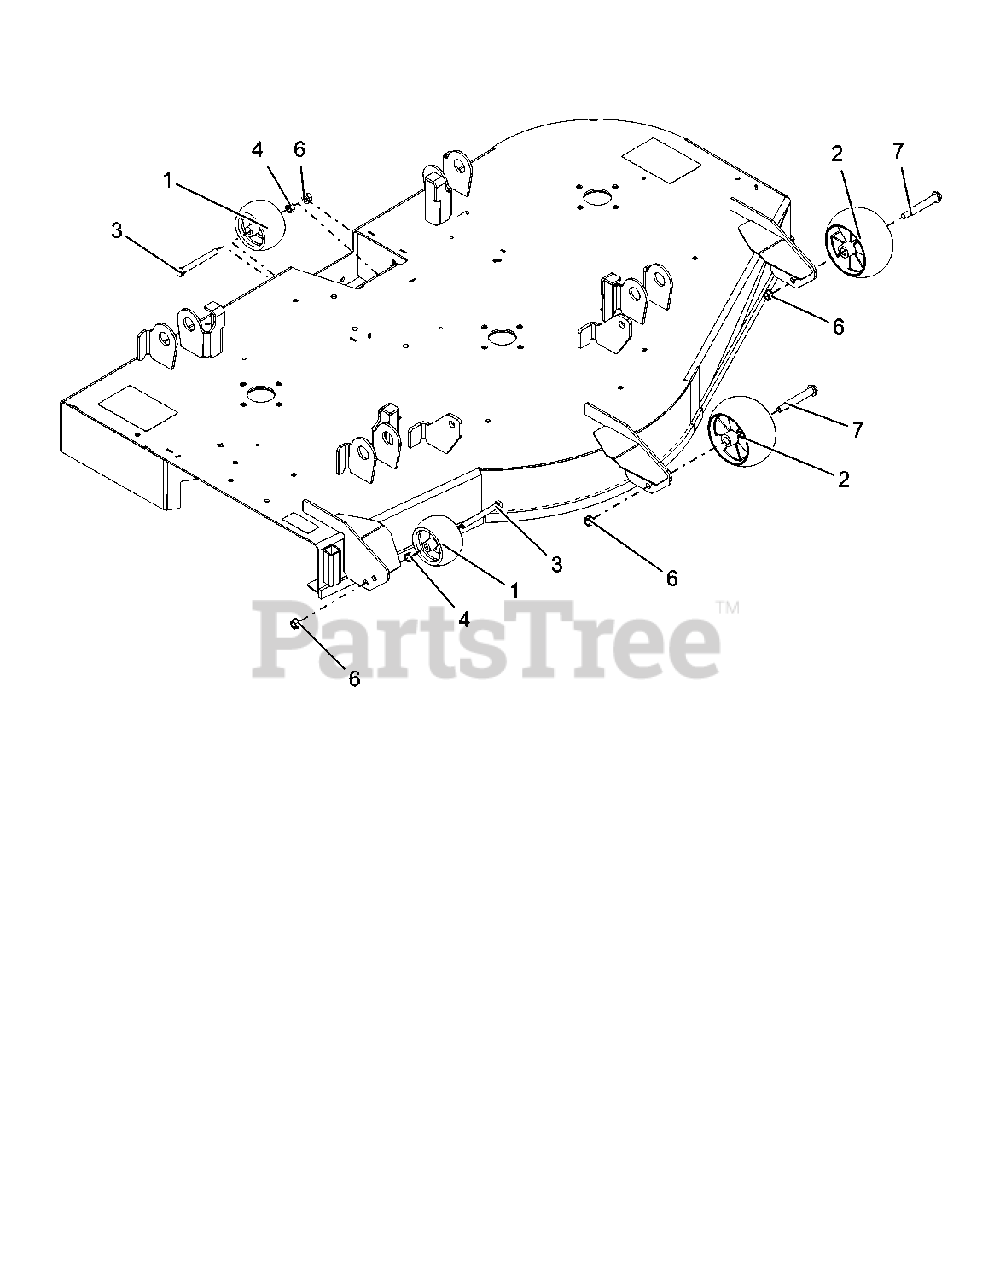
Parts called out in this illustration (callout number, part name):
2	ANTI-SCALP WHEEL - 5XOS
3	BLT-HEX .38-16X3.50 GR5 YWZC
4	NUT-HEX .38-16 YWZC
6	NUT, LK-TOP-FLG .38-16 YWZC
7	BLT-SHLDR .38-16X2.50 HWH G5YZ
